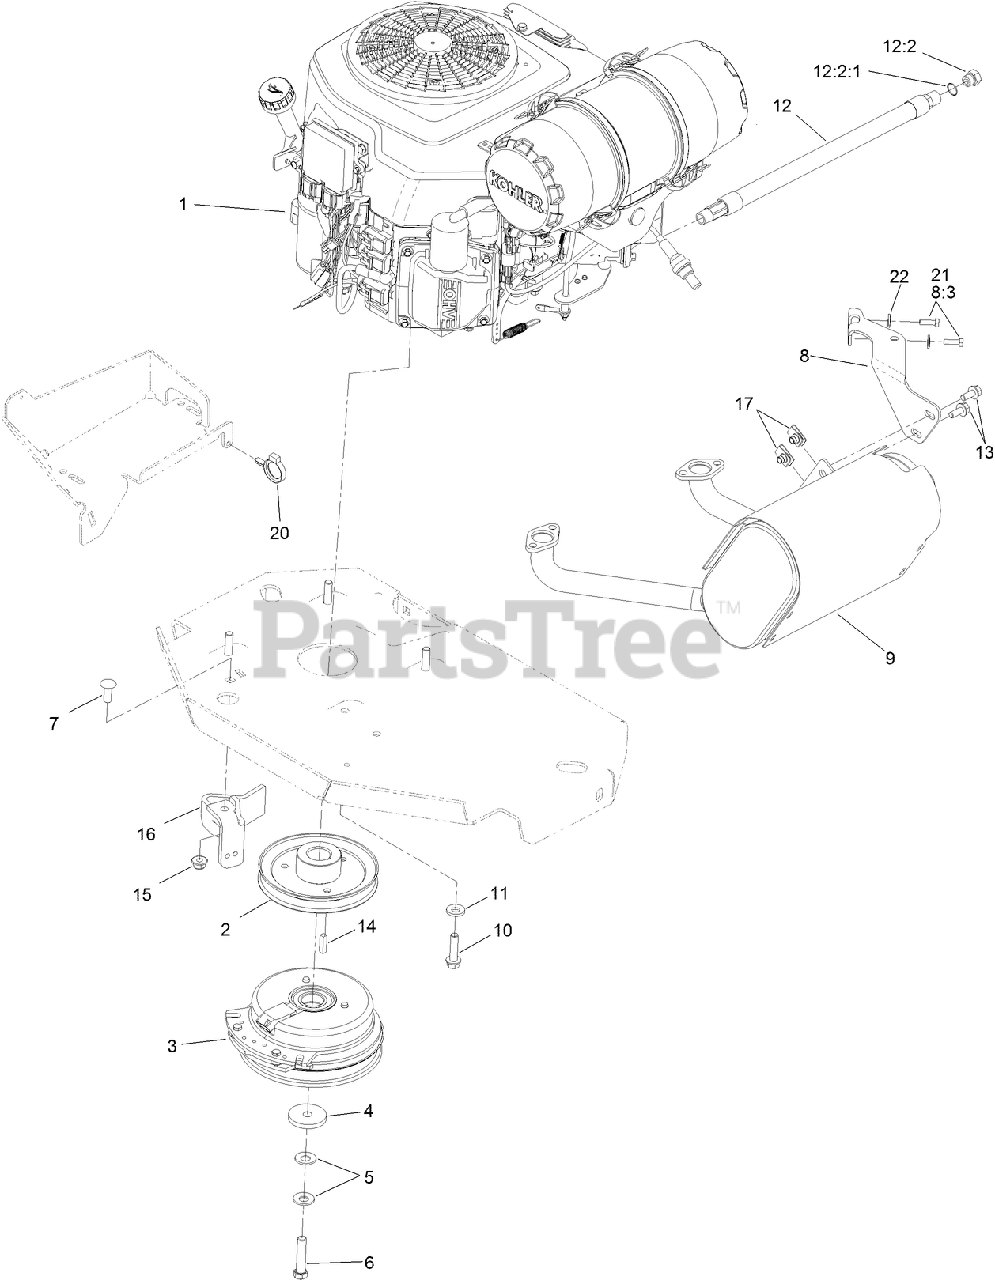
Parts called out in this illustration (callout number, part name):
1	ENGINE-KOHLER, PCV740 EFI LP
2	SHEAVE
3	CLUTCH KIT
4	WASHER-CLUTCH
5	WASHER-SPRING
6	SCREW-HH
7	SCREW-CARR
8	MUFFLER BRACKET KIT
8:3	SCREW-HH
9	MUFFLER
10	SCREW-HWH
11	WASHER-BELLEVILLE
12	OIL DRAIN HOSE ASM
12:2	PLUG-HH
12:2:1	O-RING
13	SCREW-HHF
15	NUT-HF, NI
16	CLUTCH-ANCHOR
17	NUT-U
20	CLAMP-HOSE
21	SCREW-HH
22	WASHER-SPRING
